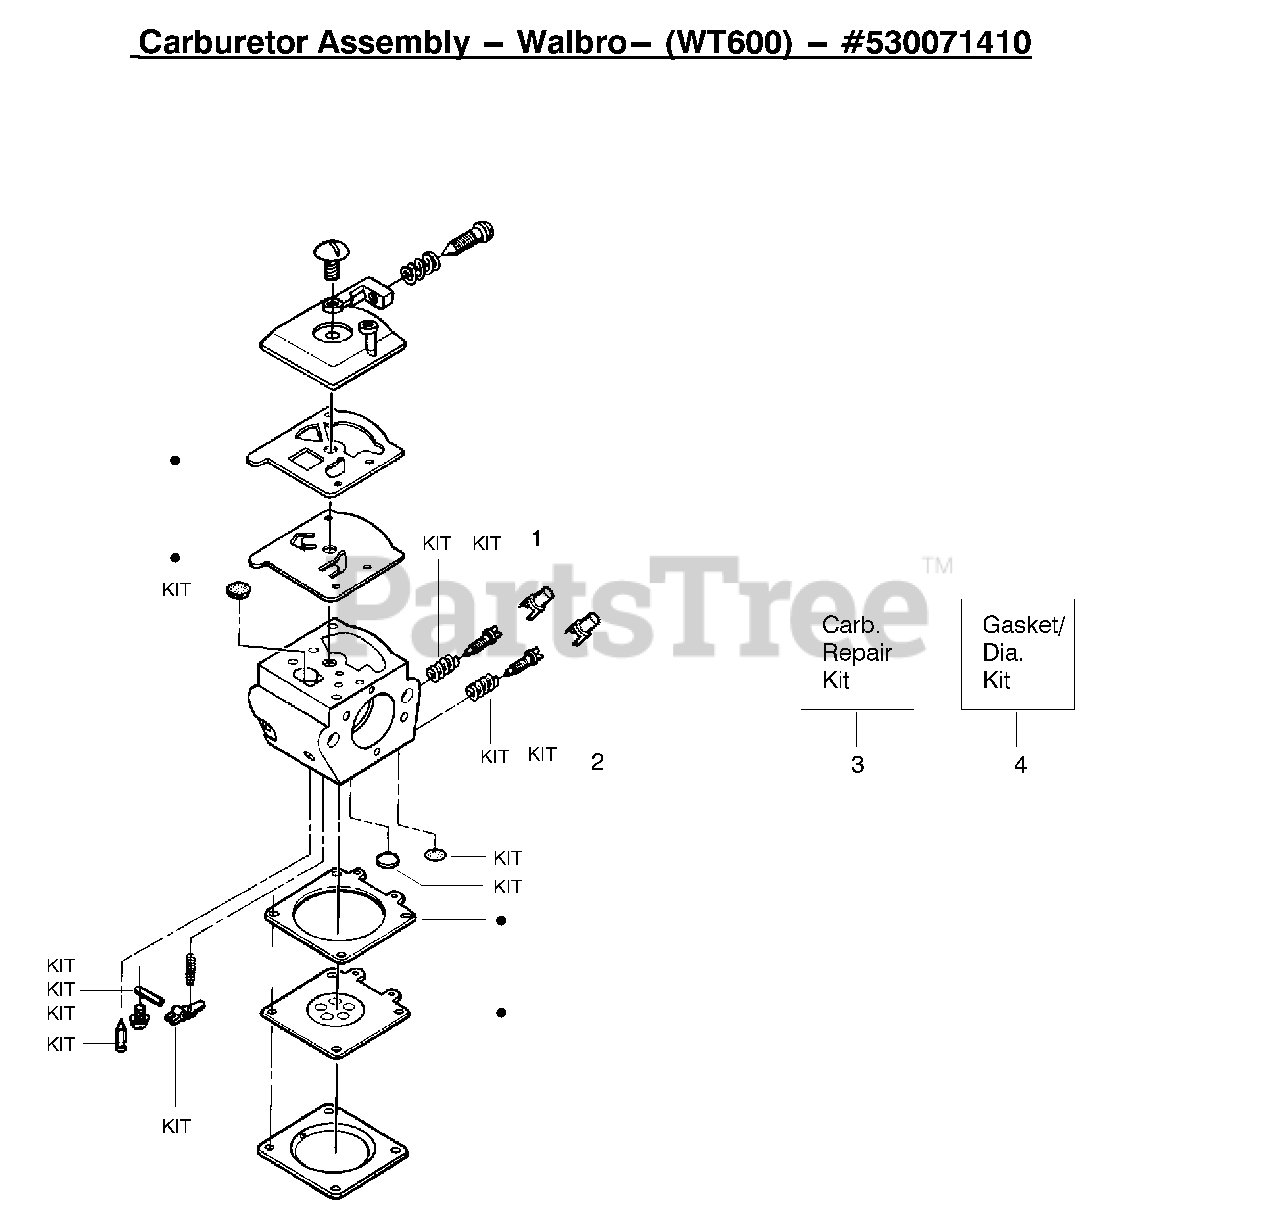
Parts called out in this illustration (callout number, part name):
1	Limiter Cap-High
2	Limiter Cap-Low
3	Carburetor Repair Kit
4	Gasket Diaphragm Kit
